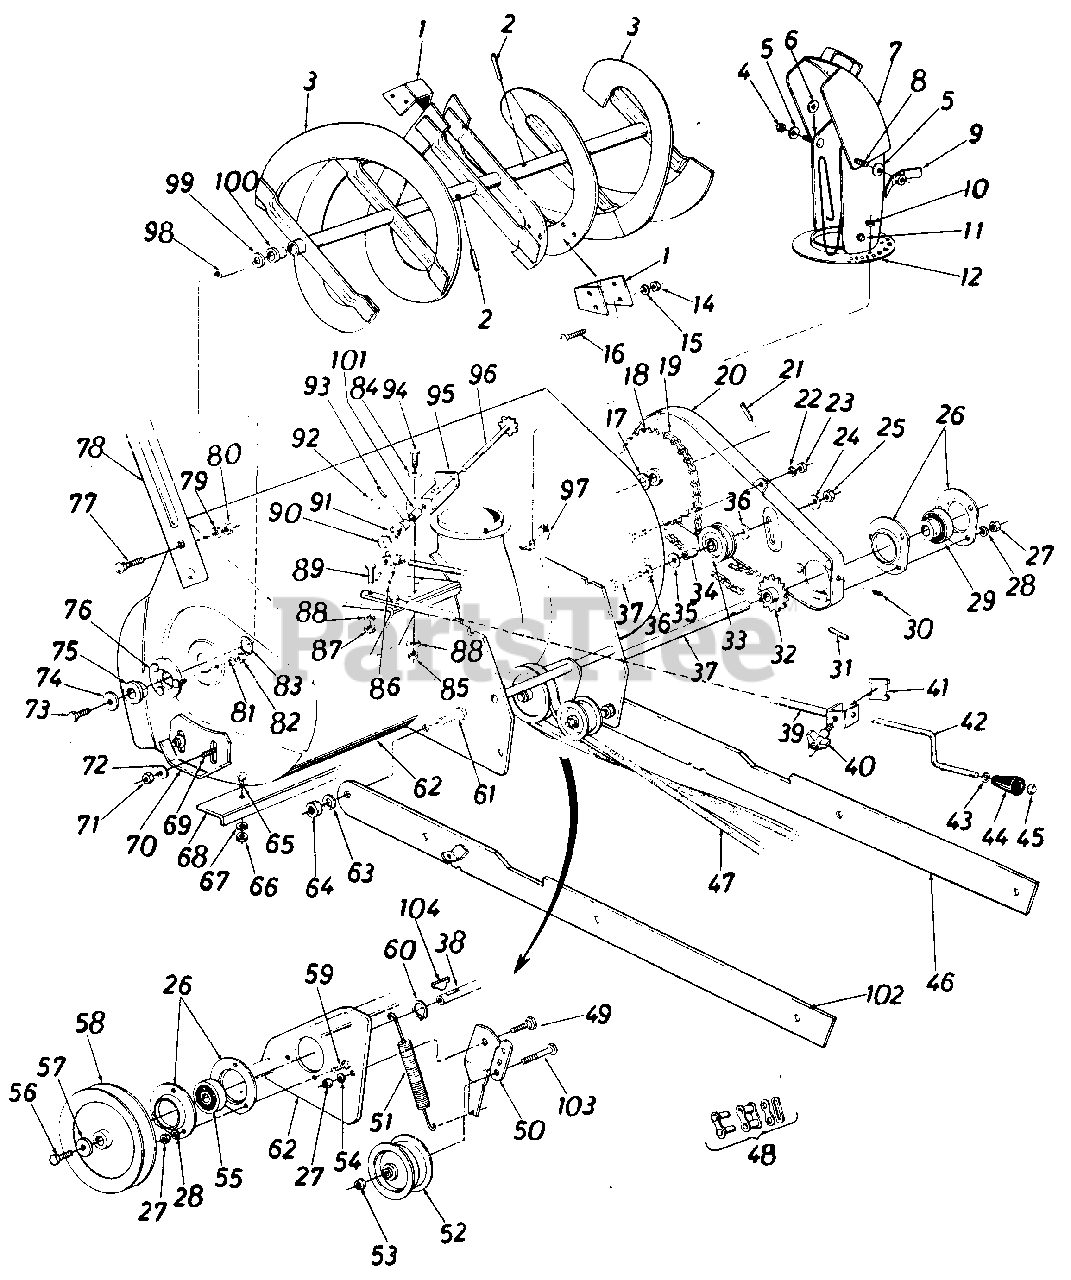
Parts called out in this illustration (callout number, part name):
1	Spiral Plate
2	Spring Pin Spir. 5/16 x 1.75" Lg.
3	Spiral Ass'y.
4	Hex Cent. L-Nut 5/16-18 Thd.
5	Bell. Wash.
6	Fl-Wash.
7	Top Chute Ass'y.
8	Car. Bolt 5/16-18 x .62" Lg.
9	Chute Wing Ass'y.
10	Hex Cent. L-Nut 1/4-20 Thd.
11	Push Cap.188" Dia. Rod
12	Chute Ass'y.
14	Hex Nut 5/16-18 Thd.
15	L-Wash. 5/16" Scr.
16	Car. Bolt5/16-18x.62" Lg.
17	Fl-Wash.
18	Sprocket Hub Ass'y 40 Teeth
19	#420Chainx 1/2" Pitch .77 Links
20	Chain Guard Ass'y.
21	Spring Pin Spir. 5/16
22	L-Wash. 5/16" Scr.
23	Hex Nut 5/16-18 Thd.
24	Bell. Wash.
25	Hex Ins. L-Nut 3/8-16 Thd.
26	Bearing Housing
27	Hex Nut 5/16-18 Thd.
28	L-Wash. 5/16" Scr.
29	Self Aligning Brg. w/Set Scr.
31	Spring Pin Spir. 5/16x 1.75
32	14 Teeth Sprocket Ass'y.
33	1.875" Dia. Flat Idler
34	Idler Spacer
35	Fl-Wash.
36	Fl-Wash.
37	Hex Scr. 3/8-16x 2.00" Lg.
38	Drive Shaft
39	Crank Support Tubing Ass'y.
40	Hand Knob 5/16-18 Thd.
41	Chute Crank Brkt.
42	Chute Crank
43	Fl-Wash.
44	Knob-Black 3/8" Dia. Hole
45	Push Nut 3/8" Rod
46	Linkage Arm Ass'y.
47	"V"-Belt 1/2" x 85" Lg. (Kevlar)
48	Master Link for #420 Chain
49	Shoulder Scr.
50	Idler Brkt. Ass'y.
51	Extension Spring
52	Fl. Idlerwith Flange
53	Hex Ins. Jam Nut 3/8-16 Thd.
54	L-Wash. 5/16" Scr.
55	Self Aligning Brg.
56	Hex Scr. 5/16-18 x .62" Lg.
57	Fl-Wash.
58	5.50 O.D. x 5/8 Pulley
59	Hex Sems Scr. 5/16-18 x .75"
60	Snap Ring for.75 Dia. Shaft
61	HexScr. 1/2-13x 1.25" Lg.
62	Spiral Housing Ass'y.
63	L-Wash. 1/2" Scr.
64	Hex Nut 1/2-13 Thd.
65	Car. Bolt 5/16-18 x .62" Lg.
66	Hex Nut 5/16-18 Thd.
67	L-Wash. 5/16'l Scr.
69	Car. Bolt 3/8-16 x .75" Lg.
72	Bell. Wash.
73	Hex Scr. 5/16-18x.62" Lg.
74	Fl-Wash.
75	Flange Brg. with Flats
76	Brg. Housing Ass'y.
77	Car. Solt 5/16-18 x .62" Lg.
78	Guide Blade
79	L-Wash. 5/16" Scr.
80	Hex Nut 5/16-18 rld
81	L-Wash . 5/16-18 Scr.
82	Hex Nut 5/16-18 Thd.
83	Snap Ring for 1.50" Dia. Shaft
84	Bell. Wash.
85	Hex Nut 5/16-18 Thd.
86	Cotter Pin 3/32 x 1.00" Lg.
87	Hex Nut 5/16-18 Thd
88	L-Wash. 5/16" Scr.
89	Hex Scr. 5/16-18 x 1.50" Lg.
90	Joint Block
91	Joint Brkt. Ass'y.
92	Spring Pin Roll 3/16" x .81" Lg.
93	Spring Pin Roll 1/8 x .75" Lg. *
94	Hex Scr. 5/16-18 x .75" Lg.
95	Chute Brkt.
96	Sprocket Shaft Ass'y.
97	Chute Flange Keeper Ass'y.
98	Spiral Axle
99	Fl-Wash.
100	Plastic Bushing
101	Spacer .380 I.D. x .630 O.D. x .565
102	Li n kage Arm Ass'y.-R.H.
103	Hex Bolt 3/8-16 x 1.75" Lg.
104	#61 Hi-Pro Key
